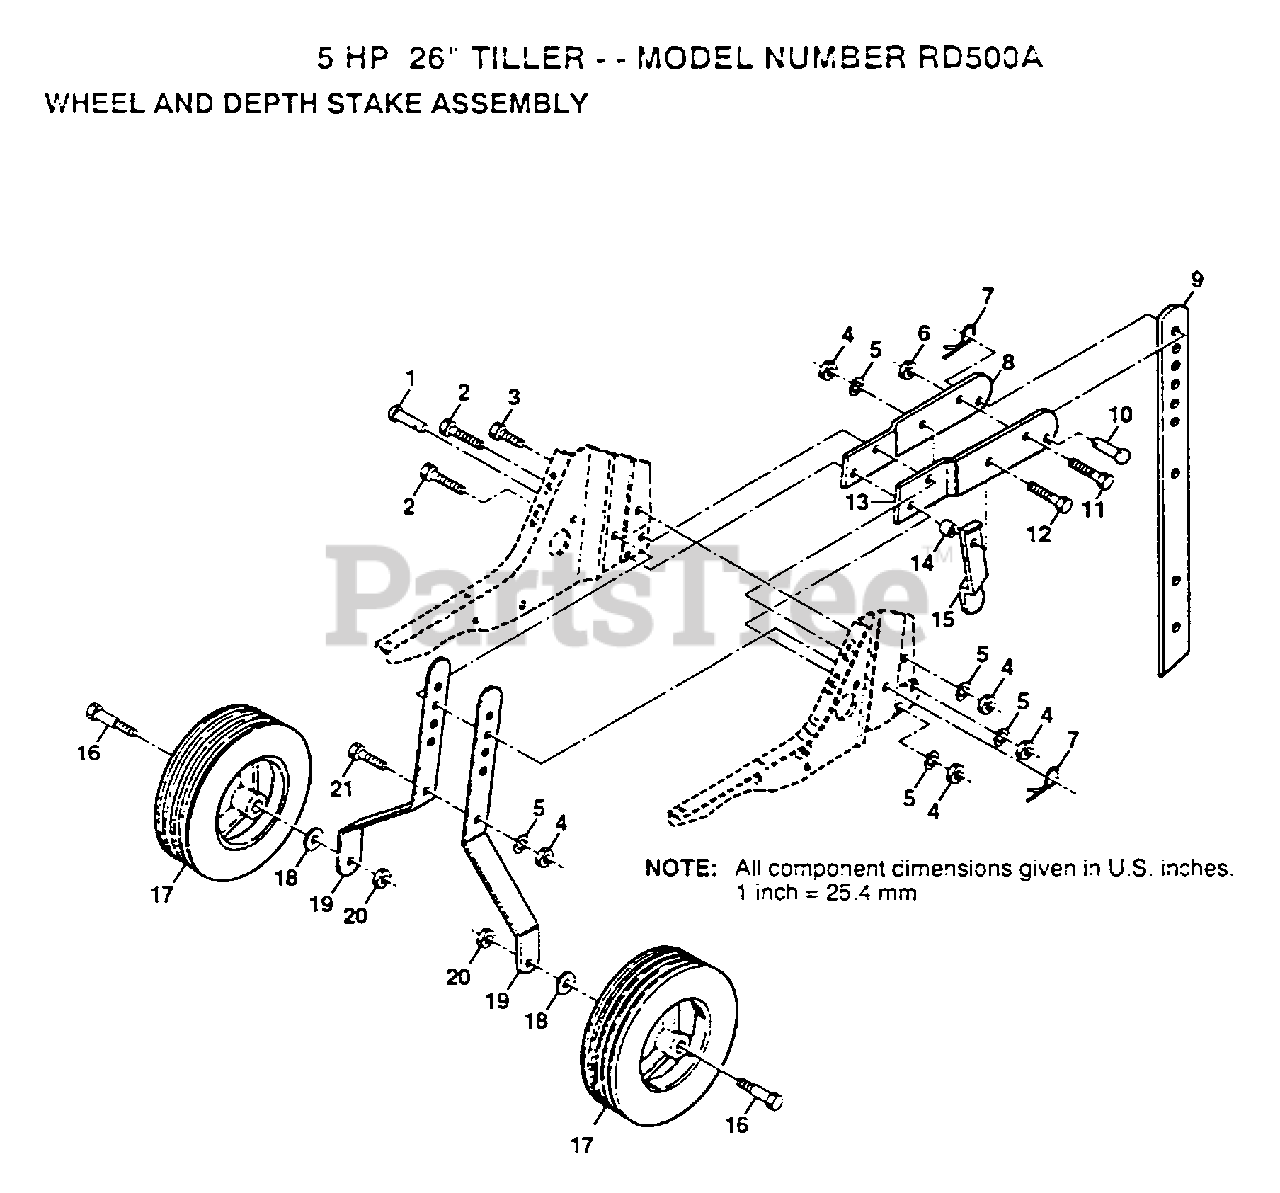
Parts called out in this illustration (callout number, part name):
1	DRILLED RIVET RT
3	BOLT
4	NUT.HEX.5/16-18
5	LOCKWASHER
6	GRIPCO NUT
7	SPRING.RETAINER
11	BOLT.3/8-24X1-1/2
12	BOLT.HEX.5/16-1.5
14	WASHER
15	STAKE SPRING TI
16	BOLT SHOULDER
18	WASHER
